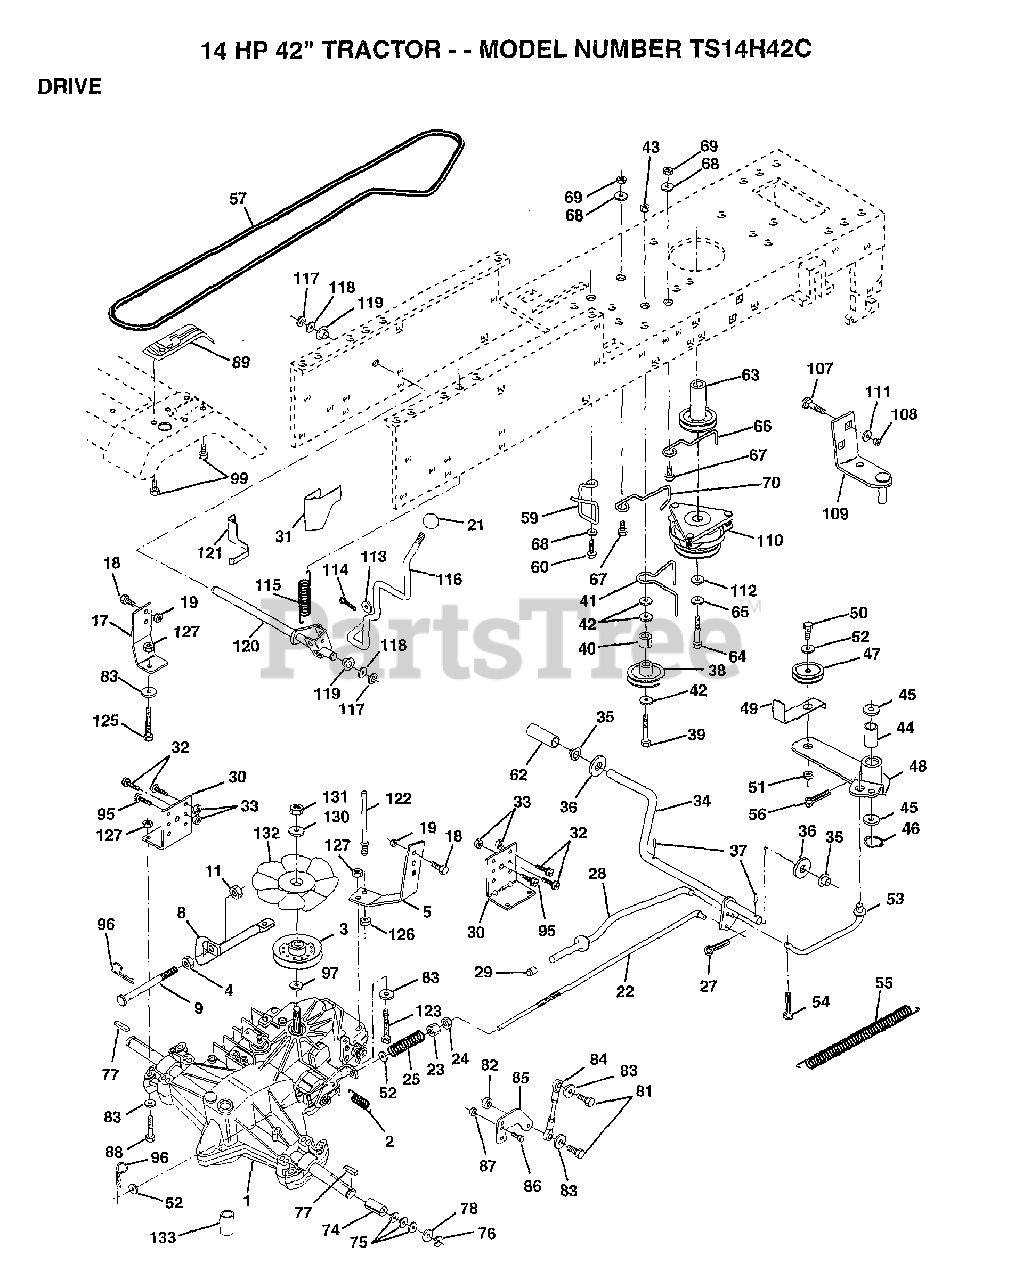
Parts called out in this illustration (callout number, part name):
2	SPRING RET BRAKE
4	JAM NUT TI
5	STRAP TORQ RH HYD
11	NUT
17	STRAP TORQ LH HYD
18	BOLT
19	NUT
21	KNOB.DUCKHEAD.1/2
23	NUT
24	NUT
25	SPRING ROD LT
27	COTTER PIN
28	BRAKE PARK ROD
29	PLUNGER CAP T
30	TRANSAXLE MTG BKT
31	"KEEPER,BELT LH T"
32	BOLT
33	NUT
35	NYLON BEARING
36	WASHER LT
38	PULLEY.IDLER.FLAT
39	BOLT
40	SPACER T
41	BELT KEEPER LT
42	WASHER
43	NUT
44	"LY, BEARING"
45	WASHER LT
46	KLIP RING
48	ARM IDLER
49	RETAIN BELT
52	WASHER
53	"LINK, CLUTCH T"
54	COTTER PIN
55	"SPRING, RETURN LT"
56	COTTER PIN
57	"BELT.GD DRV 82"""
59	KEEPER BELT CNTSP
60	SCREW
62	PEDAL COVER T
63	PULLEY CLU ELEC
65	LOCKWASHER
66	KEEPER BELT ENGLH
67	BOLT
68	WASHER
70	"KEEPER,BLT ENG LT"
74	SPACER SPLIT
75	WASHER
76	E-RING LT
77	SQUARE KEY
78	WASHER
81	BOLT
82	NUT
83	WASHER M
84	ROD.TIE.BALL.4.75
85	ARM CONTROL HYDRO
86	SCREW CAP 5/16-18
87	NUT
88	BOLT HEX
95	SCREW
96	RETAINER M
97	WASHER..562X1.0
99	SCREW HEXWSH H-L
107	BOLT
109	BRACKET.ASM.MTG
111	WASHER T
112	WASHER
113	WASHER
114	PIN COTTER 1/8
115	"SPRING,TORSION"
116	ROD SHIFT FEND LT
117	KLIP RING
118	WASHER D
119	BUSHING
121	KEEPER BELT LH
122	BOLT KEEPER RH
125	HEX BOLT
126	NUT
127	NUT
130	WASHER BELLEVILLE
131	NUT NYLON 1/2-20
132	"FAN 7"" HYDRO"
133	"LINE FUEL HYD 4"""
